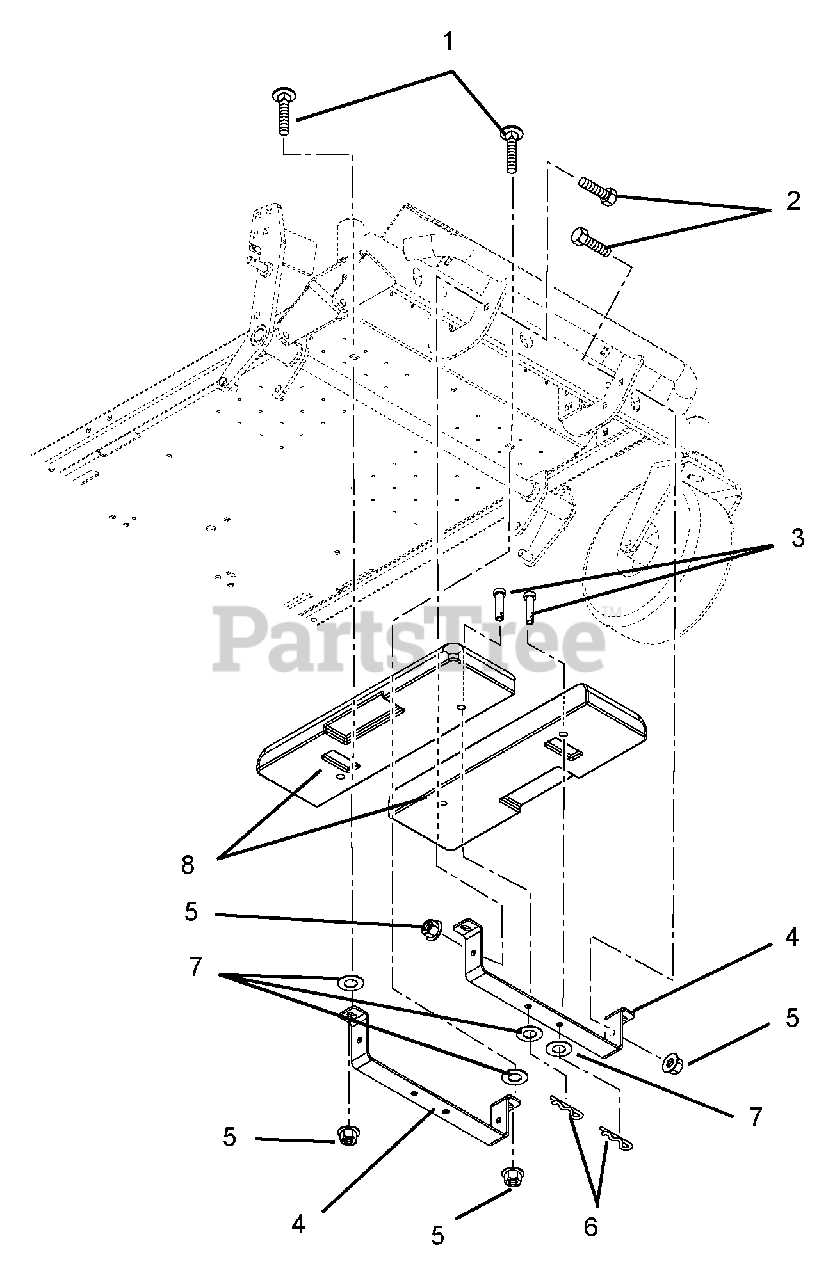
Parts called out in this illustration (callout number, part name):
1	@BLT-RDHDSQNK .38-16X1.00 G5YZ
2	@BLT-HEX .38-16X1.00 GR5 YWZC
3	PIN-CLEV .494X2.50 BRIGHT ZINC
4	BRACKET,WEIGHT
5	@NUT-LK-TOP-FLG .38-16 YWZC
6	PIN-HAIR-EXT .12X.31X2.37 YWZC
7	WSHR-FL-STL .515X1.625X.250 YZ
8	WEIGHT, CAST IRON
